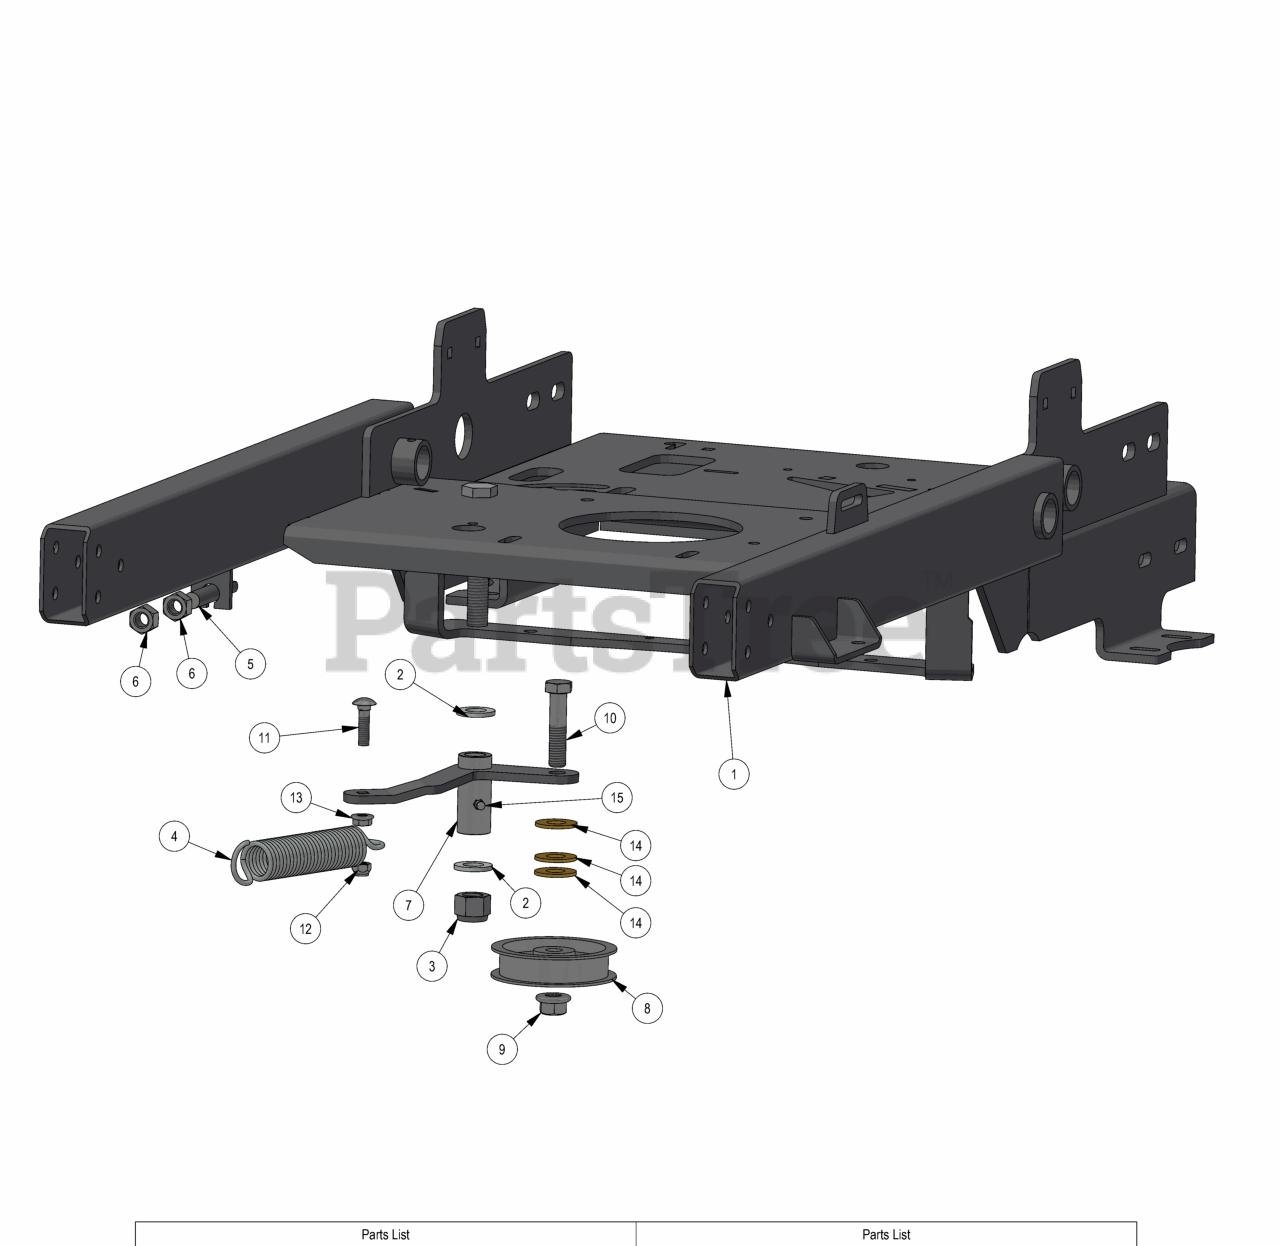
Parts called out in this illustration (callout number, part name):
1	2020 36" Stand On Frame
2	.630 ID Plastic Washer
3	5/8 Std NC Nylock Nut
4	Deck spring big diameter
5	All Thread
6	1/2-13 HEX NUT ZINC
7	36 Pump Idler Arm Weldment
8	3.25 Flat Idler Pulley
9	1/2-13 NYLON INSERT FLANGE LOCKNUT ZINC
10	1/2-13 X 2-1/4 HEX CAP SCREW (GR.5) ZINC
11	5/16-18 X 1-1/4 CARRIAGE BOLT ZINC
12	5/16-18 NYL INS L/N ZC
13	5/16-18 HEX SERRATED FLANGE NUT HARD/ZINC
14	.565 ID X 1.250 OD X .095 THK FLAT WASHER BRASS
15	1/4 DRIVE-TYPE STRAIGHT GREASE FITTING ZINC
